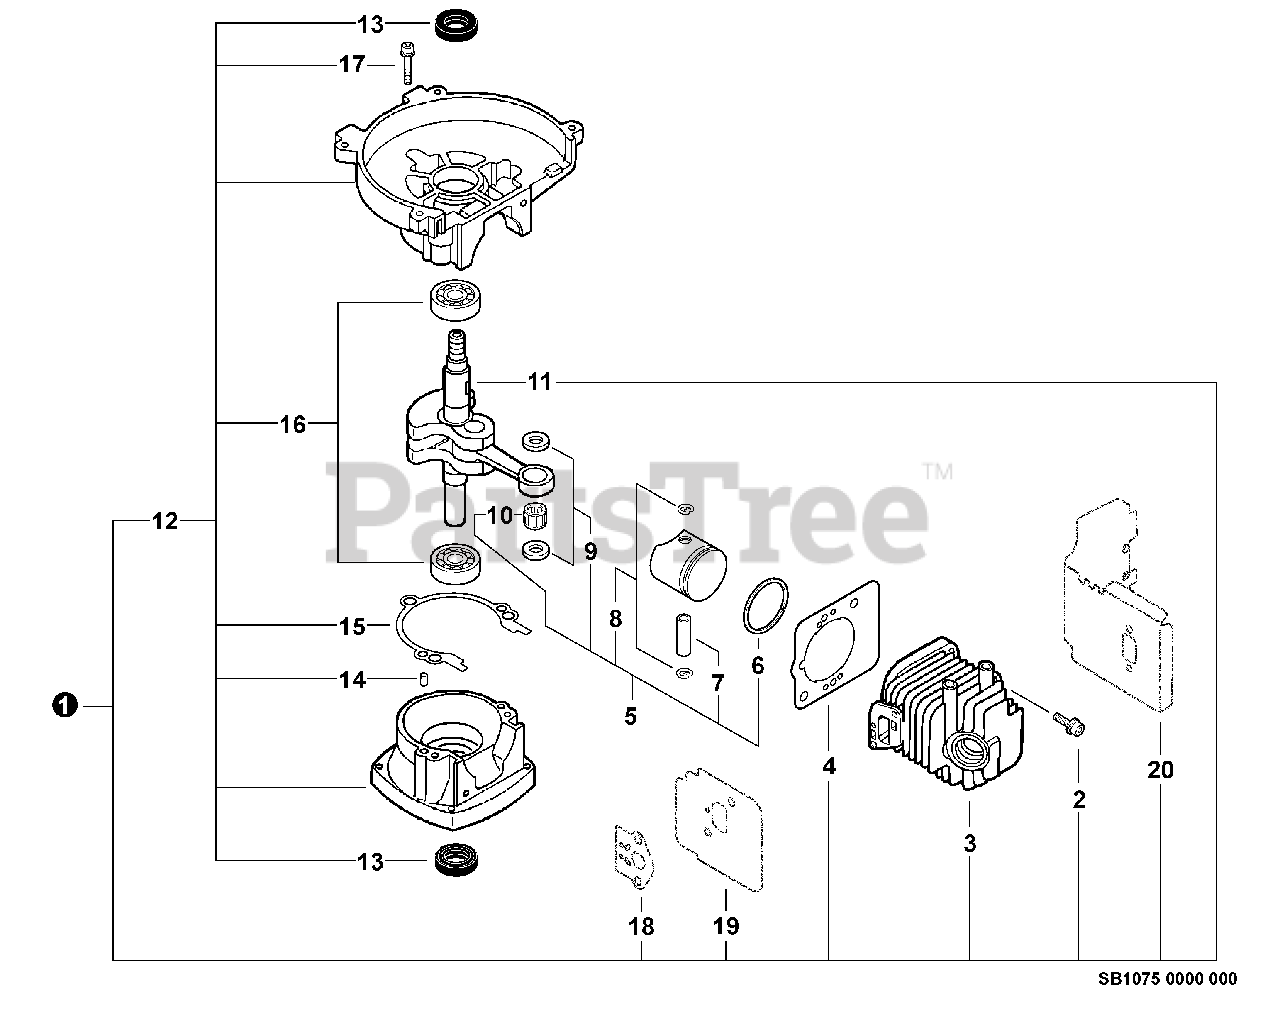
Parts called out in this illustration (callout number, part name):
1	SHORT BLOCK -- SB1075
2	SCREW - 5X22
3	CYLINDER
4	GASKET, CYLINDER
5	PISTON KIT
6	RING, PISTON
7	PIN, PISTON
8	RING, RETAINING
10	BEARING, NEEDLE - 8
11	CRANKSHAFT ASSY
12	CRANKCASE KIT
13	SEAL, OIL
14	PIN - LOCATING
15	GASKET, CRANKCASE
16	BEARING, BALL - 6201
17	SCREW - 5X28
18	SHIELD, EXHAUST
19	SHIELD, INTAKE
20	GASKET, INTAKE
